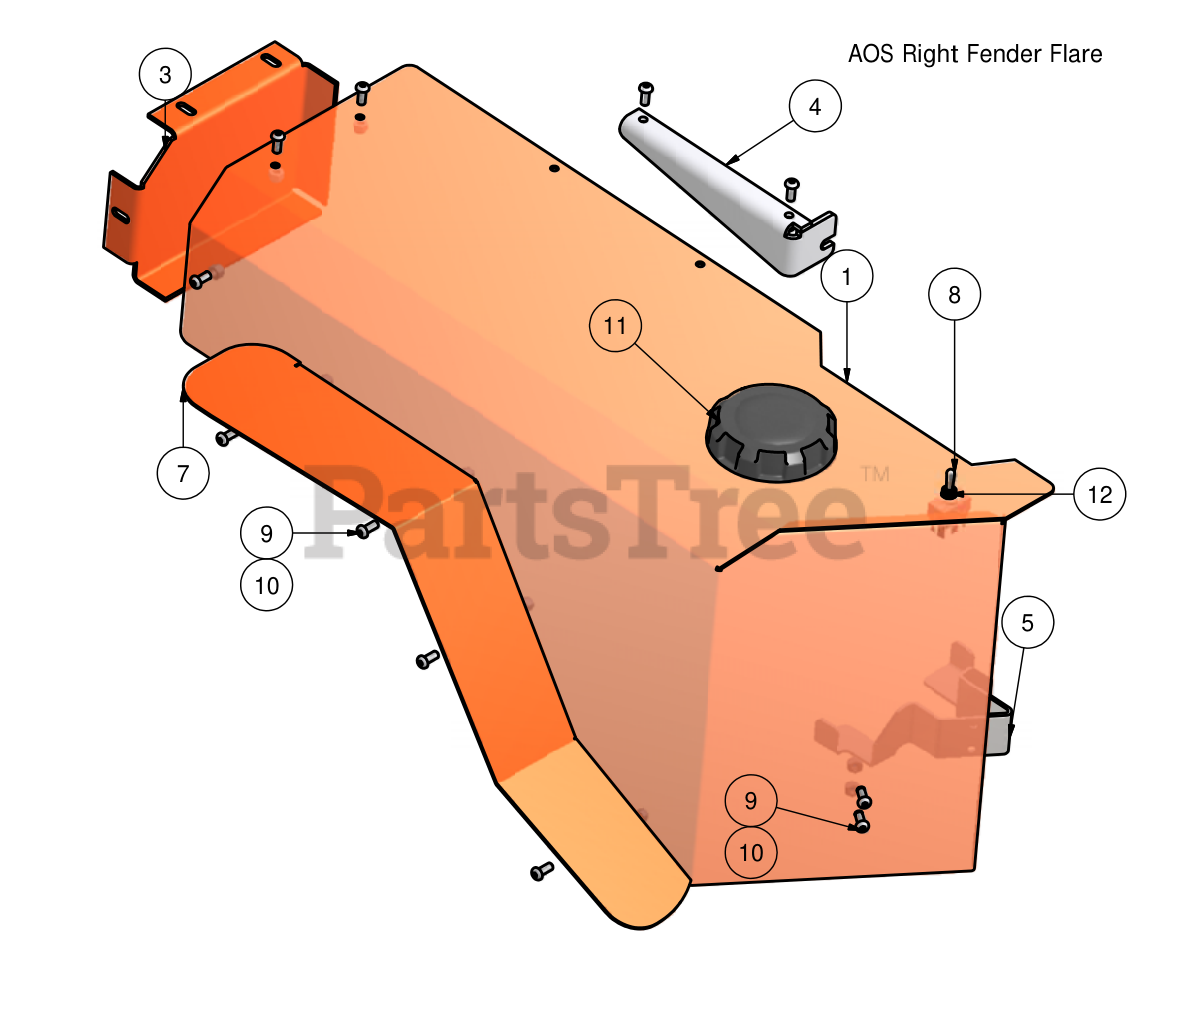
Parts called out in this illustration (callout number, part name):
1	Right fender
2	5 Gallon Fuel Tank
3	Right end tank bracket
4	Right tank retainer (5 gallon)
5	Front Retainer (Right)
6	Right Tank Retainer
7	2007 Fender Flare Right
8	Joystick (deck lift)
9	1/4" x 5/8" Buttonhead Bolt
10	1/4" Nylock Nut
12	Joystick Cover
